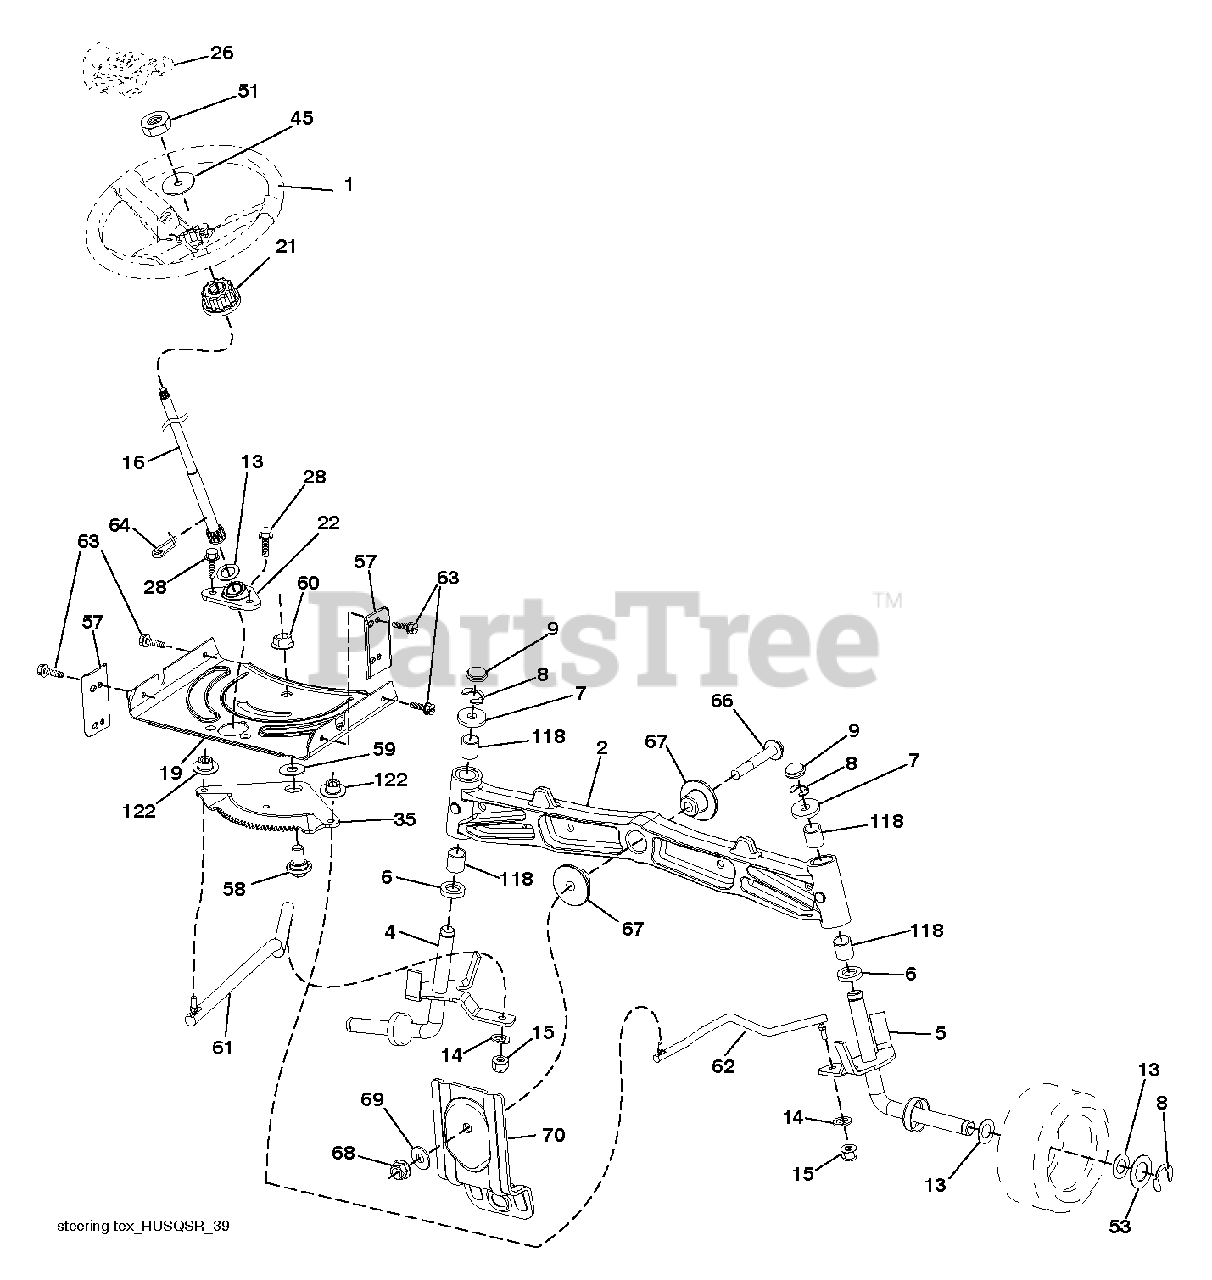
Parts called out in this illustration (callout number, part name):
1	WHEEL.STEER.HUSQ.SR.498.OVMLD
2	AXLE.SVC.ASM CAST IRON.TEX
4	SPINDLE.WELDED.LH.15"TEX
5	SPINDLE.WELDED.RH.15"T
6	THRUST WASHER
9	CAP.SPINDLE.BLACK
14	WASHER, LOCK 3/8
15	NUT CROWNLOCK 3/8-24
16	SHAFT.STEER.STEALTH.DD
19	PLATE.STEER.DDL.NLT/NG
21	ADAPTER, WHEEL STNG..
22	STEERING.SUPT.LOWER.
26	INSERT.CAP.WHL.STRG.HUSQ.PREM
28	SCREW, 3/8-16X3/4
35	GEAR.SECTOR.PLATE.DDL.
45	WASHER 9/16"ID, 2 3/8"OD
51	NUT.HEX.1/2-20
53	WASHER.HARDENED
57	BRACKET.UPSTOP.TEX
58	BOLT.SHOULDER.SECTOR.P
59	WASHER.THURST.SECTOR.S
60	NUT FLANGE LOCK 5/8-11
61	DRAGLINK.LH.BALLSTUD.D
62	DRAGLINK.RH.BALLSTUD.D
63	SCREW
64	RETAINER.CLIP.SPRING.S
66	BOLT HEX FGHD 7/16-14 X 3 SERR
67	BUSHING.PM.FRONT AXLE
68	NUT.LOCK.FLANGE.7/16
69	WASHER.1.5X.505X.118
70	BRKT.DECK.SUSPENSION.F
118	BUSHING, AXLE CAST
122	CAP.GEAR.SECTOR.TEX
